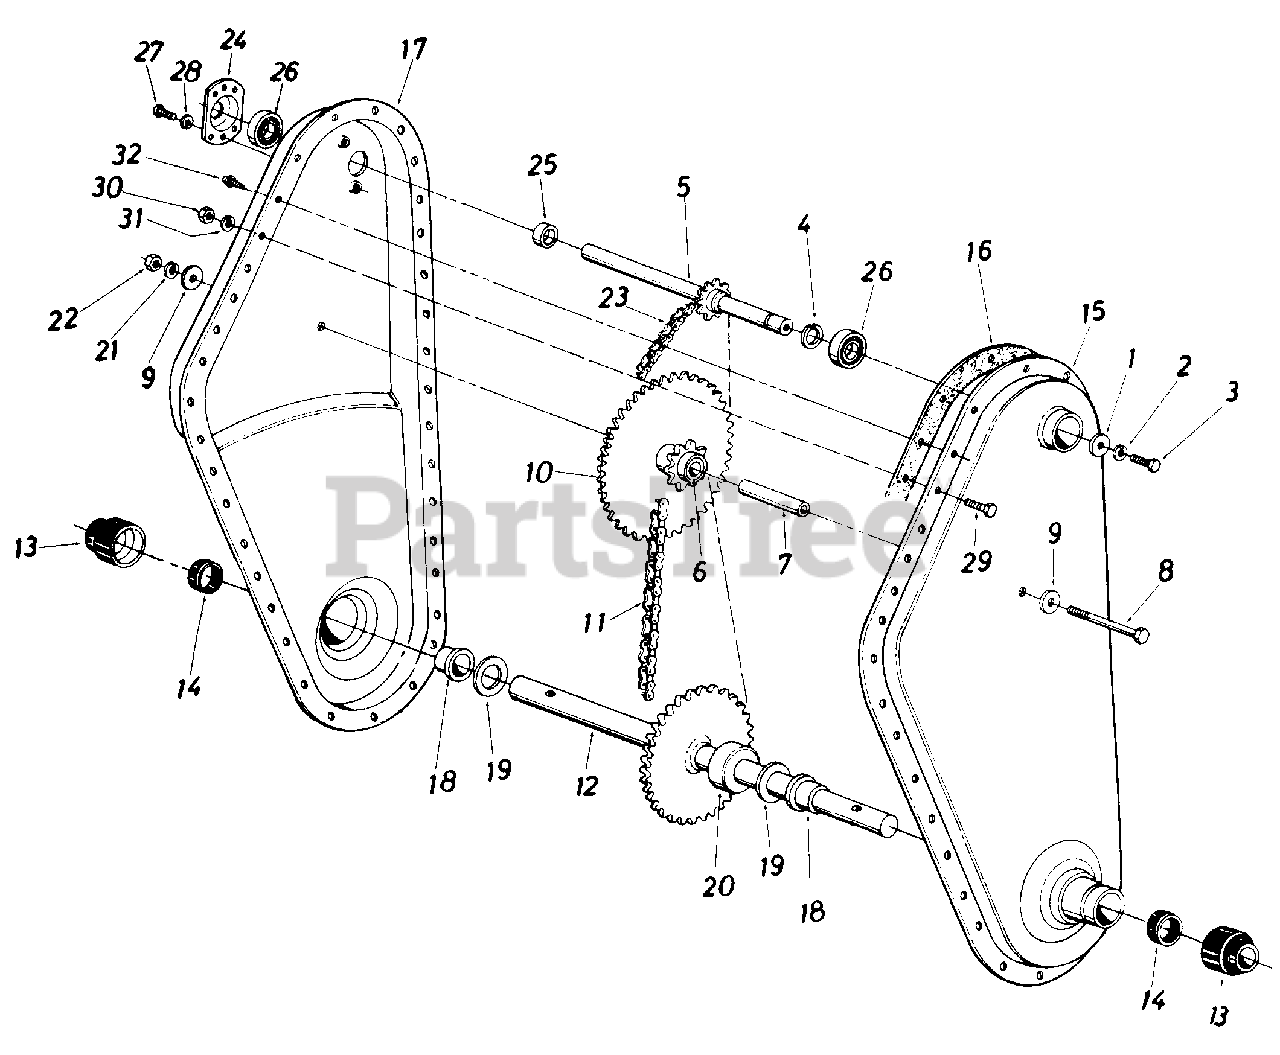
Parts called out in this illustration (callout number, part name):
1	Fl-Wash. 1/4" I.D. x .93" O.D. x .120
2	L-Wash. 1/4" I.D.*
3	Hex Bolt 1/4-28 x .62" Lg. w/Patch
4	External Snap Ring-5/8" Dia.
5	Input Shaft Ass'y.
6	Bearing 5/8" I.D. x 3/4" O.D. x 1.860" Lg.
7	Sprocket Hub Tubing 3/8" I.D. x 5/8" O.D. x 1.90
8	Hex Bolt 3/8-24 x 2.75" Lg.
9	Fl-Wash. 3/8" I.D. x 1.25" O.D. x .10
10	Sprocket Ass'y.
11	#50 Chain 5/8" Pitch x 46 0 Links Endless
12	Tine Shaft Ass'y.
13	Dust Cup
14	Seal Ring Single Lip, Springless
19	Fl-Thrust Wash. 1.0" I.D. .03 Thk.
20	Step Spacer
21	L-Wash. 3/8" I.D.
22	Hex Nut 3/8-24 Thd.*
23	#35 Chain 3/8" Pitch x 52 0 Links Endless
24	Bearing Housing 1.38" I.D.
25	Spacer
26	Ball Bearing .625" I.D. x 1.38" O.D. x .437
27	Hex Wash. SF-Tap Scr. 1/4-20 x.50" Lg.
28	L-Wash. 1/4" I.D*
29	Hex Bolt 5/16-18 x .75" Lg.
30	Hex Nut 5/16-18 Thd.
31	L-Wash. 5/16" I.D.*
32	Hex Wash. SF Tap Scr. 1/4-20 x.50" Lg.
14984-0638	HOUSING ASSEMBLY RH BLACK - MTD/TROY-BILT RED (0638)
